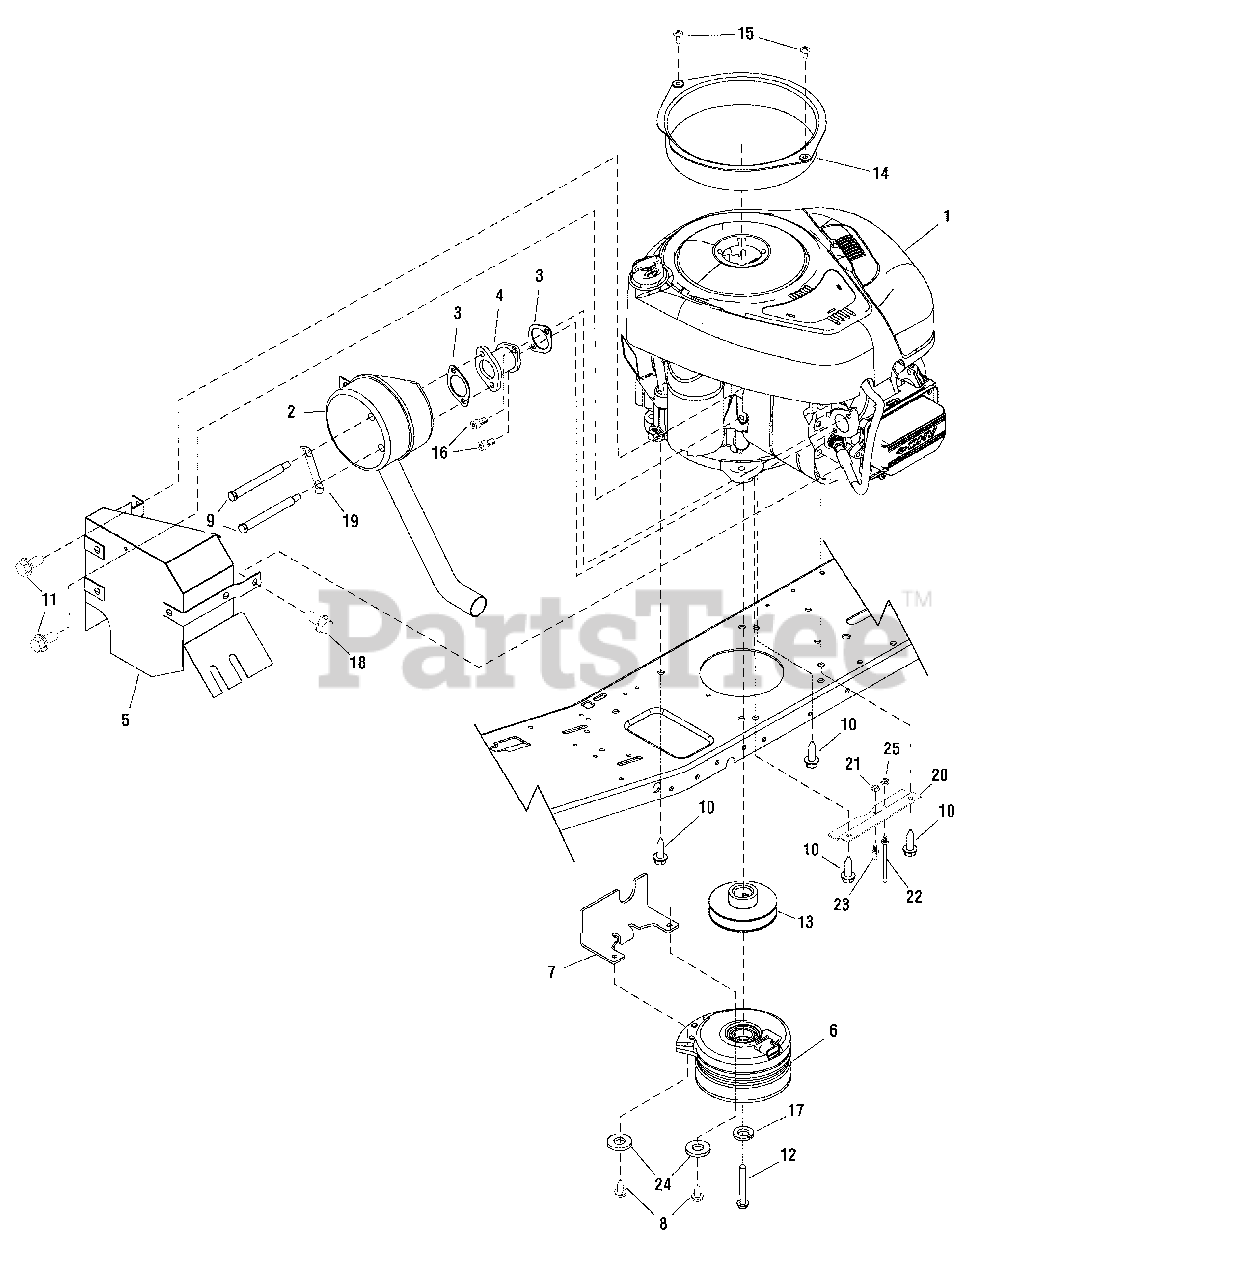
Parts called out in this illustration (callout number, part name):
1	*ENGINE, Briggs & Stratton, 15.5HP
1	*ENGINE, Briggs & Stratton, 17.5HP
2	MUFFLER
3	*GASKET 272293
4	ADAPTOR, Muffler
5	HEAT SHIELD ASSEMBLY
6	ELECTRIC CLUTCH
7	TORQUE STRAP, Electric PTO
8	CAPSCREW, 5/16-18 x 3/4
9	BOLT, Shoulder, 5/16-18 x 4.35
10	BOLT, 3/8-16 x 1-1/4
11	SCREW, Hex Head 5/16-18 x 5/8
12	CAPSCREW, Hex, 7/16-20 x 2-1/2
13	STACK PULLEY
14	BAFFLE, Engine
15	SCREW, Shoulder #10-24
16	SCREW, Torx Head 5/16-18 x 5/8
17	LOCKWASHER, Spring 7/16
18	SCREW, Hex 1/4-20 x 5/8
19	LOCK, SCREW
20	PLATE, Belt Guide
21	NUT, Flange, 5/16-18
22	GUIDE, Belt Long
23	GUIDE, Belt Short
24	WASHER, Flat, 5/16
25	NUT, Hex Flange Lock, 1/4-20
